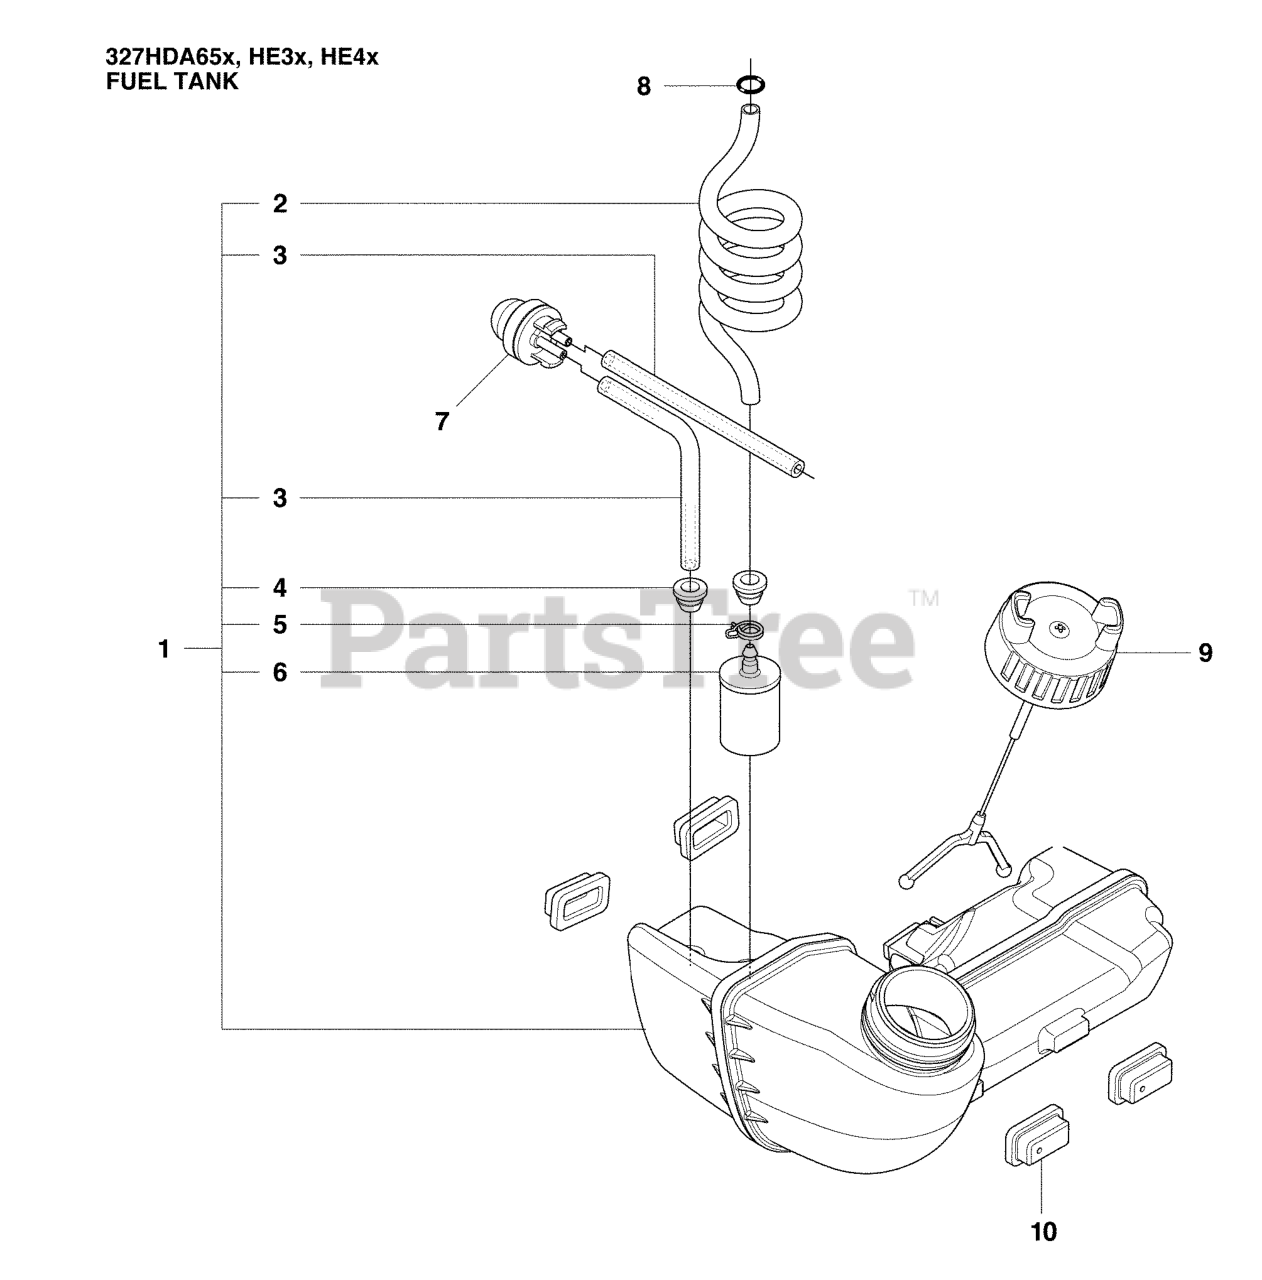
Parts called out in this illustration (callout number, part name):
1	FUEL TANK ASSY
2	FUEL HOSE
3	HOSE
4	FUEL TANK BUSHING
5	HOSE CLAMP
6	RP FUEL FILTER
7	AIR PURGE BUBBLE
9	TANK CAP
